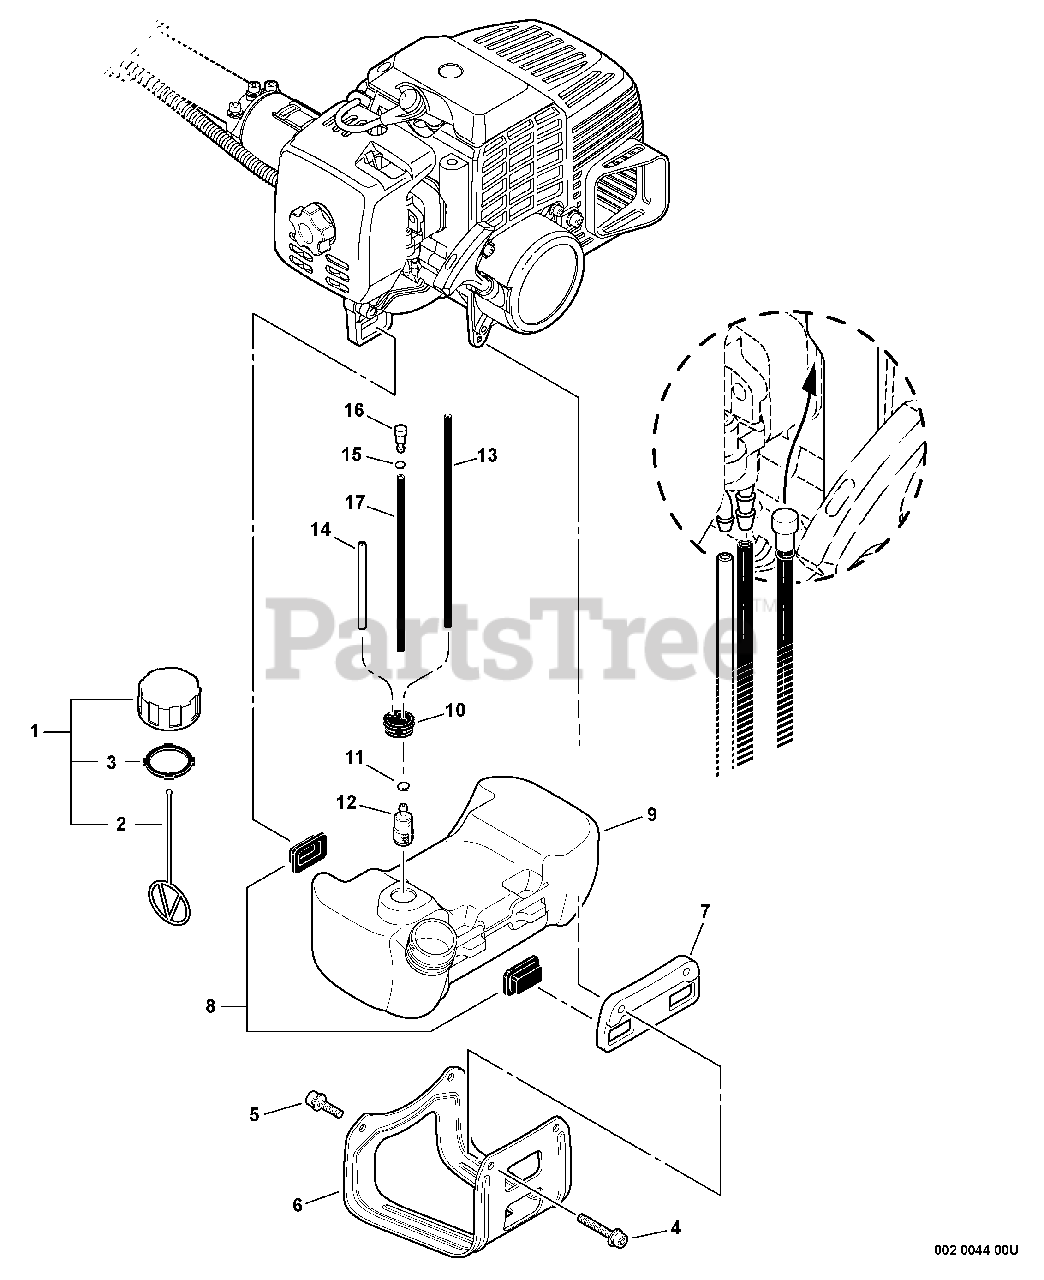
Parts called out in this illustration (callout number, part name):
1	CAP ASSY - ORANGE
2	CONNECTOR, CAP
3	GASKET, CAP
4	SCREW - 5X20
5	SCREW - 5X12
6	GUARD, FUEL TANK
7	BRACKET, FUEL TANK
8	CUSHION, FUEL TANK
9	TANK, FUEL
10	GROMMET
11	CLIP - 6
12	FILTER, FUEL
13	PIPE - 3X5X180 -- BLACK
14	PIPE - 3X6X70 -- CLEAR
15	CLIP - 5.5
16	VENT, FUEL TANK
17	PIPE - 3X5X120 -- BLACK
